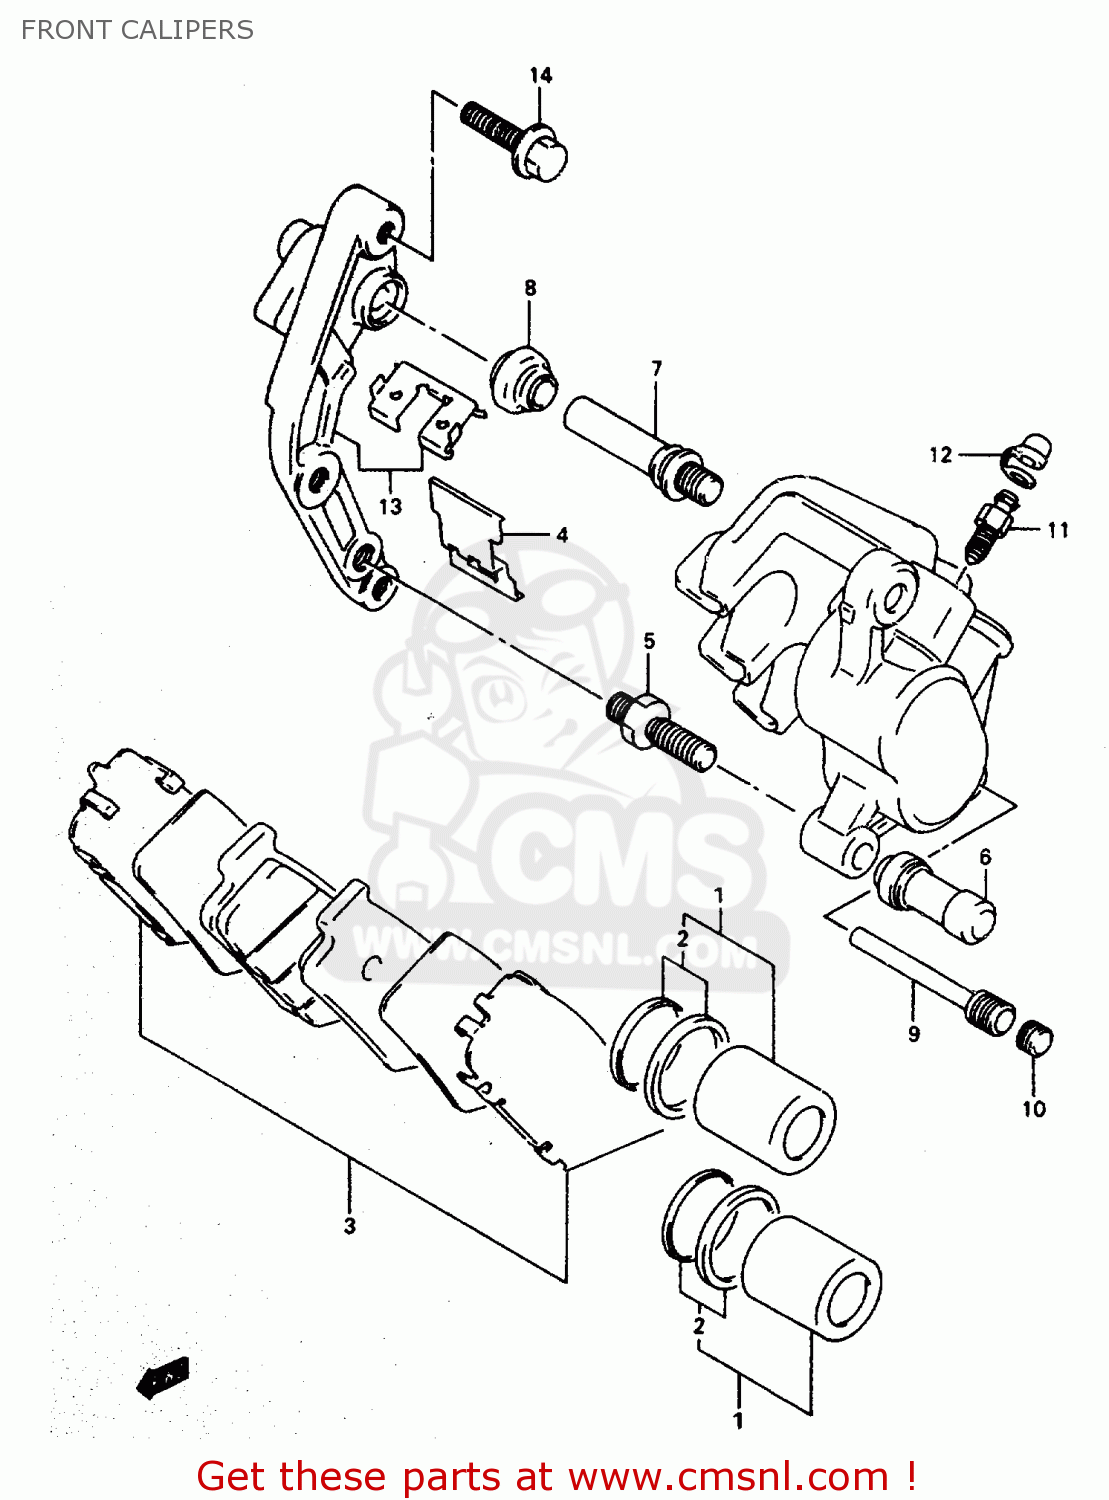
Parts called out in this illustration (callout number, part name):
00000	CALIPER ASSEMBLY,FRONT,LEFT
1	PISTON SET
2	SEAL SET,PISTON
3	PAD & SHIM SET (NAS)
4	SPRING,PAD
5	PIN,BOLT
6	BOOT
7	PIN
8	BOOT
9	PIN,HANGER
10	PLUG,PIN
11	BLEEDER
12	CAP,BLEEDER
13	BRACKET,R
14	BOLT(8X30)
